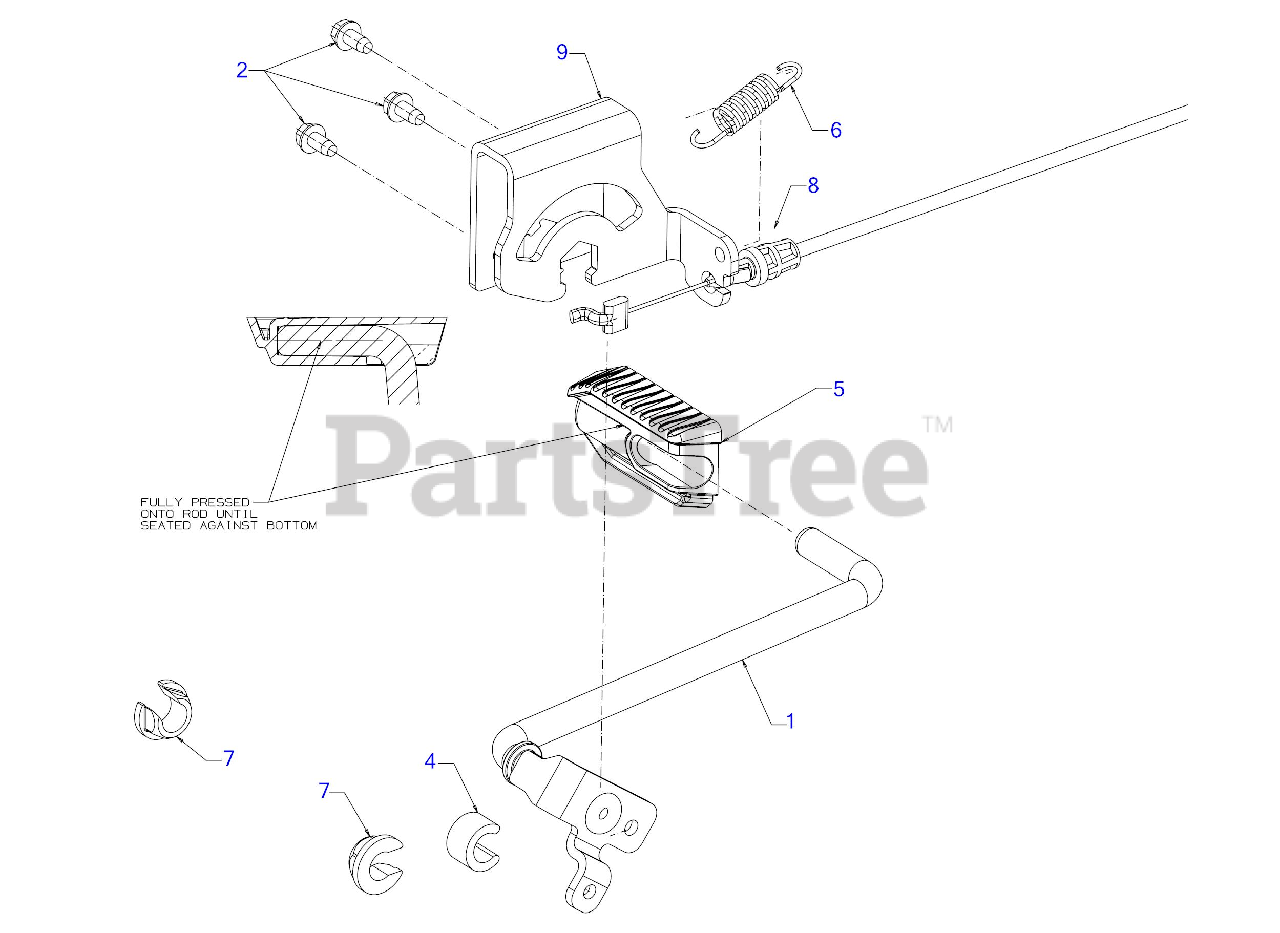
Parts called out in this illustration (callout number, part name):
1	ROD ASSEMBLY-LEVER
2	SCREW 1/4-20 X.500
4	CLIP SPACER
5	KICKSTAND COVER
6	EXTENSION SPRING
7	SPLIT HEX FLANGE BEARING
8	CONTROL CABLE 12.75"
9	KICKSTAND BRACKET
